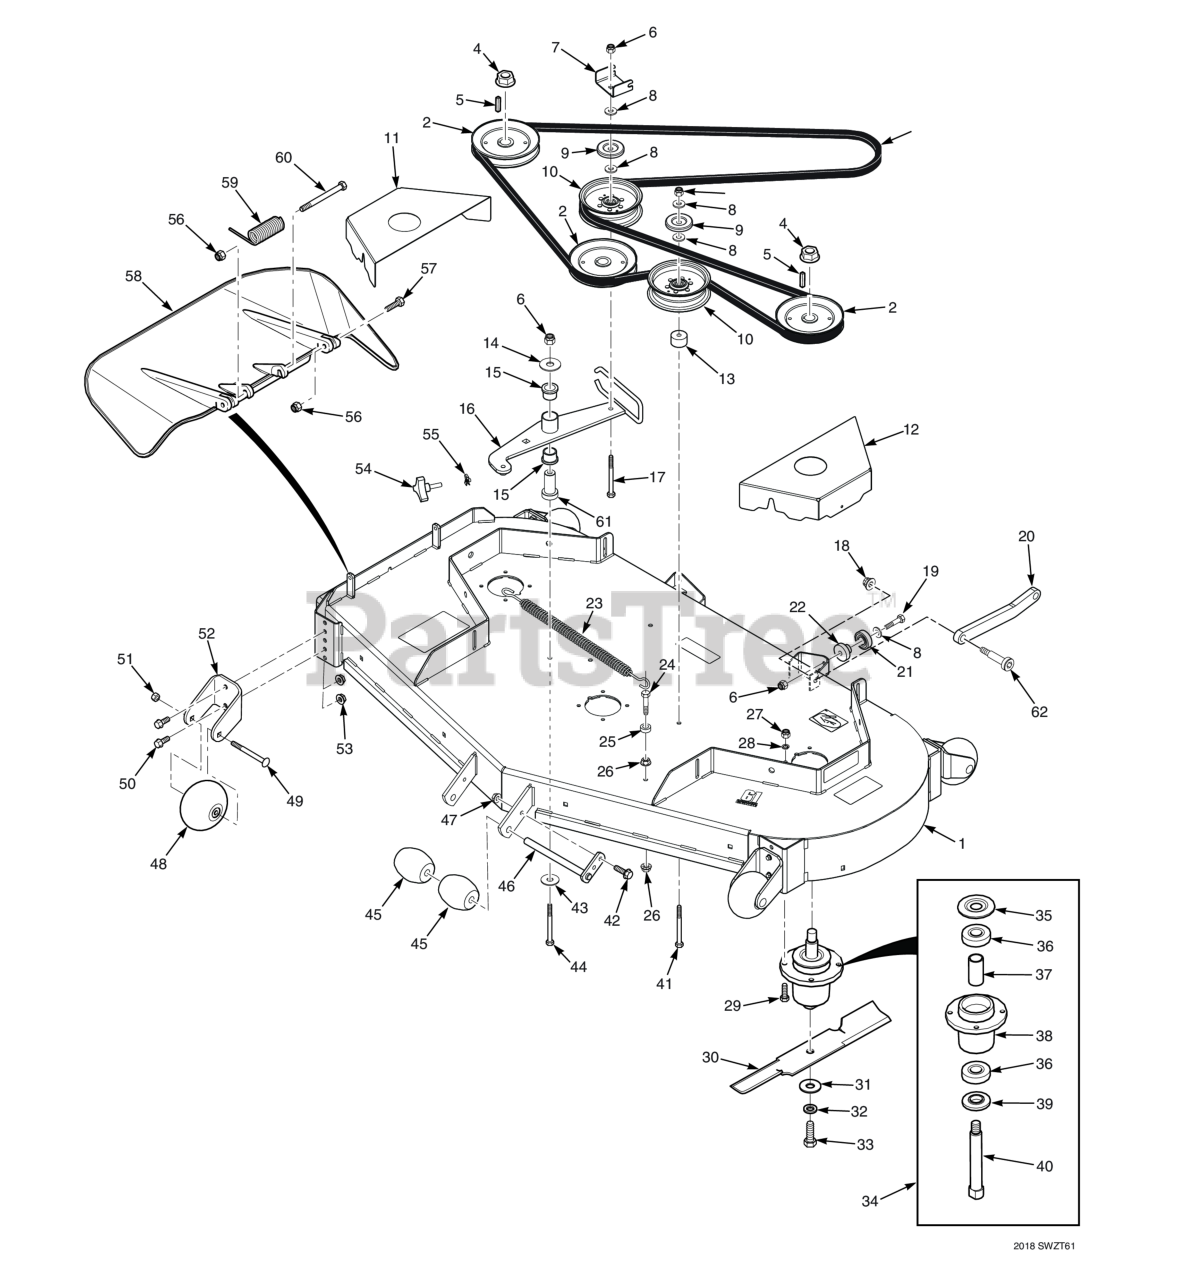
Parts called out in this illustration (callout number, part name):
1	Cutter Deck w/Decals, SWZT61
2	Pulley, 6.32" OD - 25mm Bore
3	Belt, Cutter Deck - SWZT61
4	Nut, 3/4-16 Spriral Lock
5	Key, 1/4 x 1/4 x 1.25" Pulley Mtg.
6	HEX NUT, ELASTIC STOP LOCK, 3/8-16
7	Bracket, Belt Guide
8	Flatwasher, 3/8 (.391 x .938 x .105 HD) Grade 8
9	Quick Pin, 5/16" Dia.
10	Pulley, 5" Idler
11	Belt Cover, RH - SWZT61
12	Belt Cover, LH - SWZT61
13	Spacer, Idler Pulley
14	Flatwasher, 3/8-.406 x 1-1-1/2 x 7 Gauge
15	Bearing, Plastic
16	Idler Arm Weldment w/Bearings - SWZT61
17	Capscrew, Hex Head 3/8-16 x 2-1/2"
18	Nut, Flange Elastic Stop Nut, 3/8-16
19	Bolt, Hex Head 3/8-16 x 1-3/4" (Kohler EFI)
20	Pusharm
21	Bearing
22	Spacer, Bearing
23	Spring, Cutter Deck Idler
24	Bolt, Hex Head 3/8-16 x 1-1/2" Grade 8 Black
25	SPACER, IDLER
26	NUT, 3/8-16 SERRATED FLANGE HEX HEAD
27	Lock Nut, 5/16-18 Elastic Stop Grade 8
28	Lockwasher, 5/16 (.317 x .586 x .078) Helical Spring
29	Bolt, Hex Head 5/16-18 x 1-1/2" Grade 8
30	Cutter Blade, 21" Standard
31	Flatwasher, 5/8-.688 x 1-3/4 x .134 HD
32	Lockwasher, 5/8" Spring
33	Bolt, Hex Head 5/8-11 x 1-1/2"
34	Spindle Assembly
35	Debris Shield
36	Bearing
37	Spacer, Bearing
38	Spindle Housing Assembly
39	Protector, Bearing
40	Shaft, Spindle
41	Bolt, Hex Head, 3/8-16 x 3-1/2"
42	Bolt, Heax Head 5/16-18 x 1" (48V / 52V)
43	Flatwasher, 3/8-.406 x 2.25" x .1875
44	Capscrew, Hex Head 3/8-16 x 3-3/4"
45	Wheel, Anti-Scalp
46	Shaft Weldment, Guide Roller
47	Nut, Flange Head Elastic Stop 5/16-18
48	Bolt, Carriage 3/8-16 x 4"
49	Bolt, Hex Head 3/8-16 x 3-1/2"
50	Capscrew, 3/8-16 x 1.0" Serrated Flange Hex Hd
51	Bolt, Hex Head 3/8-16 x 1" Ser. Flg.
52	Bracket, Anti-Scalp Wheel
53	NUT, 3/8-16 SERRATED FLANGE HEX HEAD
54	Knob, w/stud 3/8-16 x 1-1/4"
55	U-Nut, 3/8-16
56	HEX NUT, ELASTIC STOP LOCK, 5/16-18
57	Bolt, Hex Head 5/16-18 x 1-1/2" - Front
58	Discharge Chute Assembly
59	Spring, Discharge Chute
60	Bolt, 5/16-18 x 4-3/4" Hex Head
61	Pivot, Idler
62	Bolt, Shoulder 1/2 x 3/8-16 x 2-3/4"
